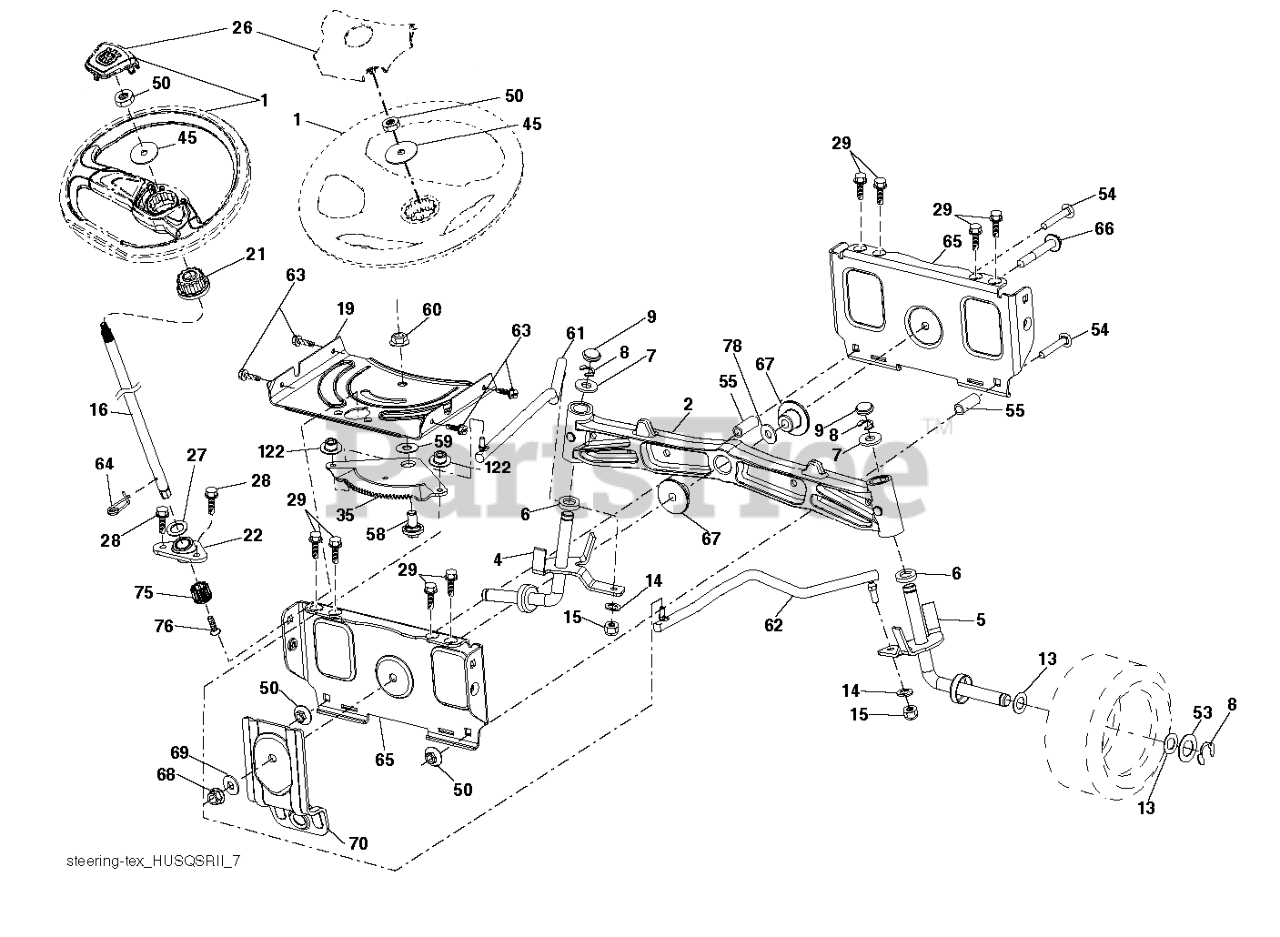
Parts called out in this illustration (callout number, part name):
1	WHEEL.STEER.HUSQ.SR.498.OVMLD
1	Service Kit
2	AXLE.CAST.IRON
4	SPINDLE.WELDED.LH.16"TEX
5	SPINDLE.WELDED.RH.16"TEX
6	WASHER THRUST
9	CAP.SPINDLE.BLACK
15	NUT CROWNLOCK 3/8-24
16	SHAFT.STEER.2HIGH.SPLND.PLATED
19	PLATE.STEER.DDL.NLT/NG
21	ADAPTER.WHEEL.STEER.SPLND.ALUM
22	BEARING.SUBASM.SHAFT.STEER.LOW
26	Steering
26	INSERT.CAP.WHL.STRG.HUSQ.PREM
27	Washers
27	WASHER LT
28	SCREW, 3/8-16X3/4
29	SCREW, 3/8-16X3/4
35	GEAR.SECTOR.PLATE.DDL.
45	WASHER.3/8ID.2-3/8OD.12GA.PLTD
50	NUT LOCK FLG 3/8-16 UNC
53	WASHER.HARDENED
55	SPACER.BRACE.AXLE
58	BOLT.SHOULDER.SECTOR.P
59	WASHER.THURST.SECTOR.S
60	NUT FLANGE LOCK 5/8-11
63	SCREW
64	RETAINER.CLIP.SPRING.S
65	BRACE.AXLE.FRONT.NLT/N
66	BOLT HEX FGHD 7/16-14 X 3 SERR
67	BUSHING.PM.FRONT AXLE
68	NUT.LOCK.FLANGE.7/16
69	WASHER.1.5X.505X.118
70	BRACKET.FRT.DECK.SUSP.RR.MT431
75	KIT.SRVC.STEERINGSHAFT.PINION
76	SCREW HEAD SOCKET LRVB
78	THRUST WASHER
122	CAP.GEAR.SECTOR.TEX
